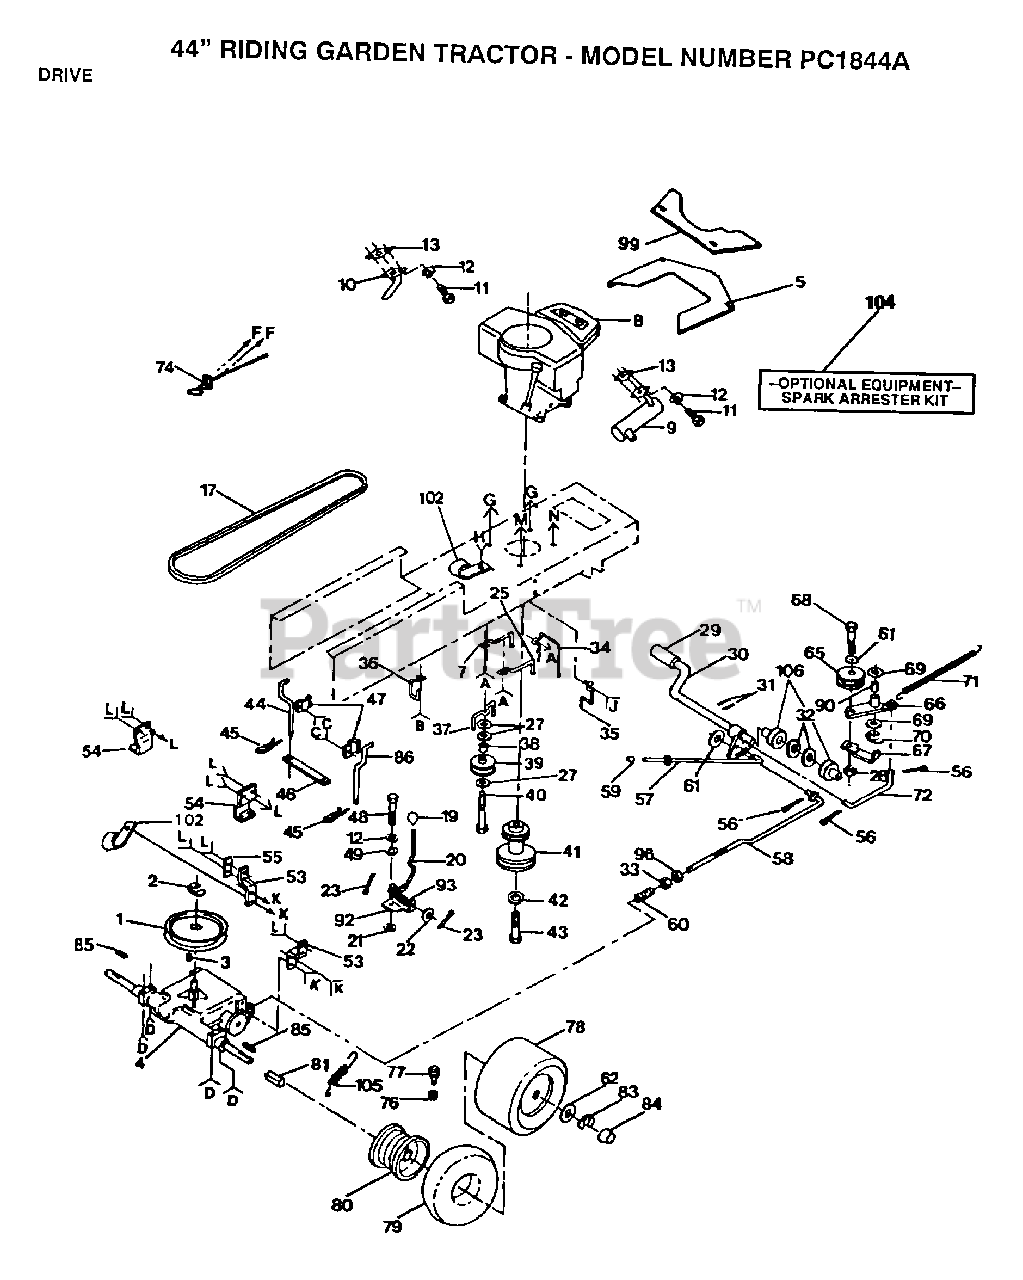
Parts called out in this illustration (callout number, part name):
1	PULLEY TRANSAXLE
2	RING
4	TRANSAXLE PEERLESS
5	SHIELD HEAT FRT
6	WASHER
7	KEEPER BELT ENGLH
10	EXHAUST TUBE T
12	LOCKWASHER
17	V BELT
19	KNOB T (1/2-HOLE)
20	ROD SHIFTER T
21	WASH-SHFT PLT LT
22	WASHER
23	PIN COTTER 1/8
24	SCREW
25	"KEEPER,BLT ENG LT"
26	BOLT
27	WASHER
29	PEDAL COVER T
32	WASHER LT
33	NUT
34	BELT GUIDE
35	BELT GUIDE
37	BELT KEEPER LT
38	SPACER T
39	IDLER.FLAT.GTV
40	BOLT
42	LOCKWASHER
43	BOLT
45	SPRING.RETAINER
46	STRAP LOCATOR
49	WASHER LT
50	BOLT
52	BOLT HEX
53	STRAP TORQUE
54	BRACKET LT
55	PLATE-STRAP LT
57	ROD BRAKE PARK
58	ROD BRAKE
59	PLUNGER CAP T
60	SPRING ROD LT
61	WASHER
62	WASHER
66	ARM IDLER
67	RETAIN BELT
69	WASHER LT
70	KLIP RING
71	"SPRING, RETURN LT"
72	"LINK, CLUTCH T"
75	SCREW LT
76	VALVE CAP
77	VALVE STEM LT
79	TUBE.18X9.5-8
81	SPACER HYT
83	E RING HYT
84	HUB CAP
85	SQ KEY STD
87	SCREW LT
90	"LY, BEARING"
92	PLATE SHIFT LT
93	SPRING LT
94	LOCKWASHER
95	NUT
96	NUT
98	WASHER
99	REAR BAFFLE T
101	SCREW
102	CLIP T
106	NYLON BEARING
